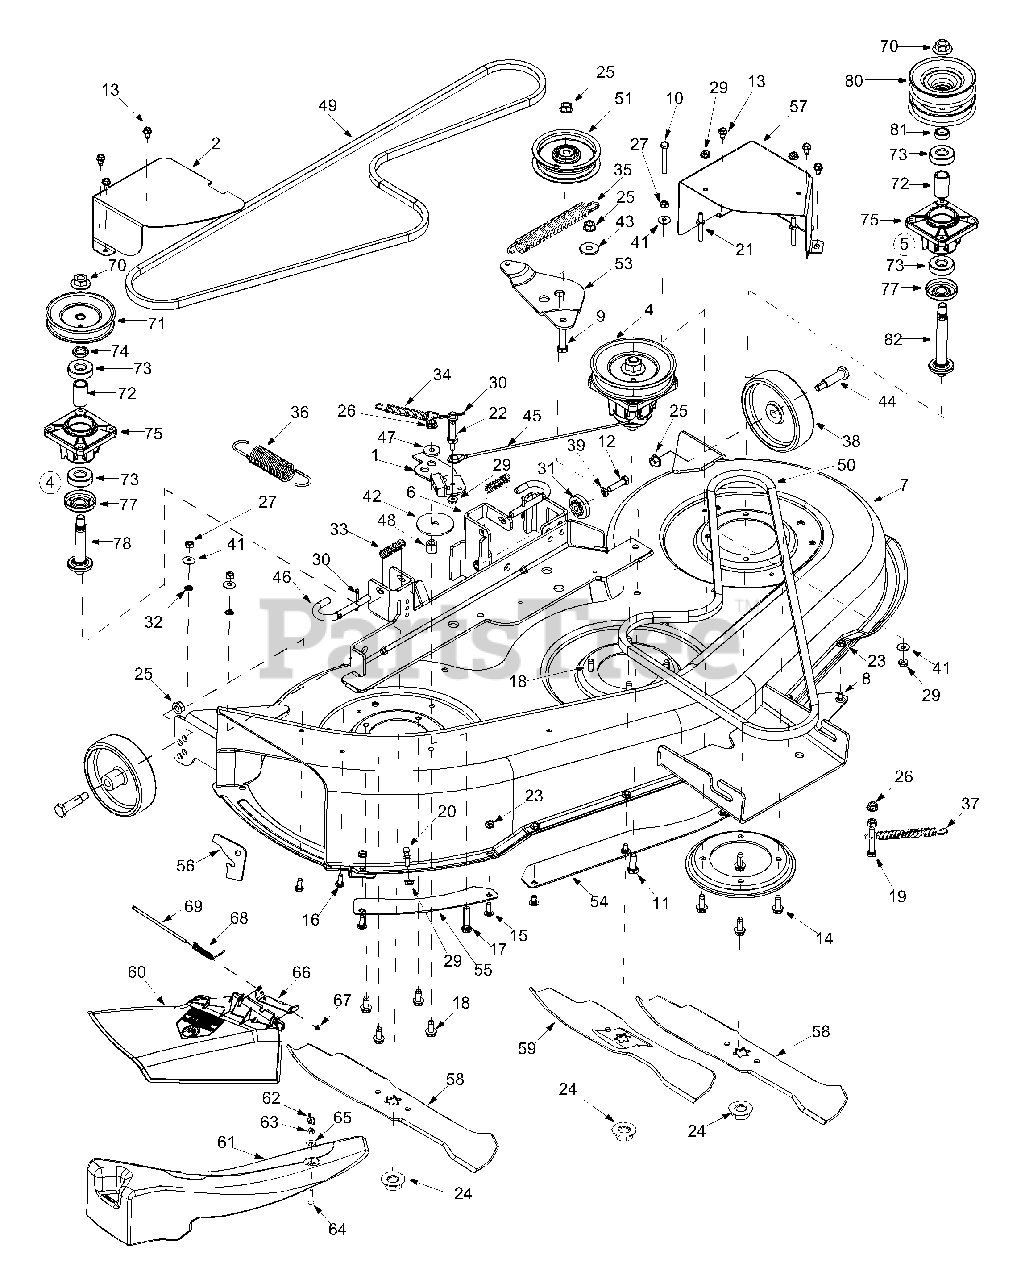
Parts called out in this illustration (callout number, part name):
1	Brake Assembly: Deck
5	Spindle Assembly: Double Pulley
9	Hex Screw 3/8-16 x 1.5"
10	Hex Screw 1/4-20 x 2.0"
11	Hex Screw 3/8-16 x 1.0"
12	Hex Screw 5/16-18 x 1.25"
13	TT Screw 1/4-20 x 0.5"
14	TT Screw 5/16-18 x 0.875"
15	Carriage Screw 1/4-20 x 0.75"
16	Hex Screw 1/4-20 x 0.620"
17	Hex Screw 5/16-18 x 1.5"
18	LD Screw 5/16-18 x 0.75"
19	Hex Screw 5/16-18 x 1.75"
20	Grass Catcher Pin
21	Belt Guard Pin
23	Hex Sems Nut 1/4-20
24	Flange Nut
25	Flange Lock Nut
26	Flange Lock Nut
27	Hex Nut 1/4-20
28	Hex Nut 5/16-18
29	Hex Flange Nut 1/4-20
30	Cotter Pin
31	Gear Adjustment
32	Push Nut
33	Compression Spring
34	Extension Spring
35	Extension Spring
36	Extension Spring
37	Extension Spring
38	Deck Wheel
39	Lock Washer
40	Flat Washer
41	Bell Washer
42	Flat Washer
43	Spacer
44	Shoulder Screw
45	Cable Bracket
46	Deck Release Handle Rod
47	Shoulder Spacer
48	Spacer
49	V Belt
50	V Belt
51	Idler Pulley
56	Chute Stop
58	Blade: 16.28" Star
59	Blade: 14.88" Star
60	Chute Deflector: Side Discharge
61	Mulch Plug
62	Wing Nut
63	Hex Nut
64	Machine Screw
65	Flat Washer
66	Mounting Bracket
67	Speed Nut
68	Torsion Spring
69	Hinge Pin
70	Flange Nut
71	Deck Pulley
72	Spacer
73	Ball Bearing
74	Spacer
75	Spindle Housing
77	Shoulder Bearing
78	Spindle Shaft
79	Flange Lock Nut
80	Pulley
81	Spacer
82	Spindle Shaft
